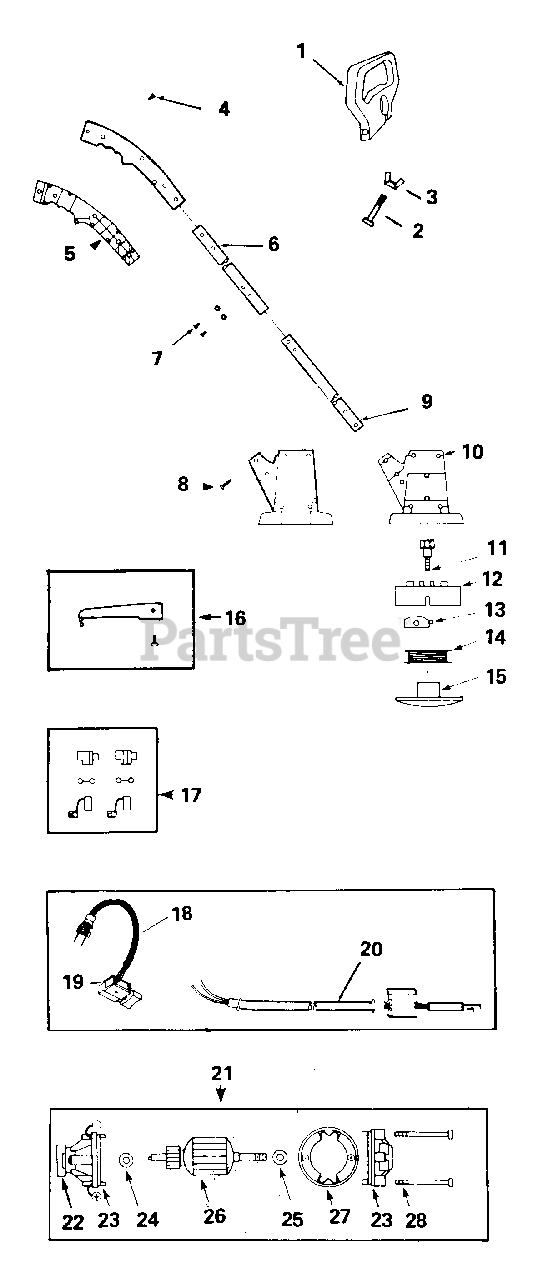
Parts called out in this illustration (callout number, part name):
1	ASSIST HANDLE
3	WING NUT
5	TRIGGER HANDLE SET
6	TUBE, UPPER
7	TUBE FASTENER KIT
9	TUBE, LOWER
10	MOTOR HOUSING SET
12	HUB w/LINE SAVERS
13	LINE SAVER
14	SPOOL, WOUND
15	BALL LOCK
16	LINE LIMITER KIT
17	BRUSH KIT
18	POWER CORD PIGTAIL
20	HARNESS w/RECTIFIER
22	INSULATOR
23	END BELL SET
24	WASHER-THRUST, .025"
25	WASHER-THRUST, .010"
26	ARMATURE
27	FIELD ASSEMBLY
